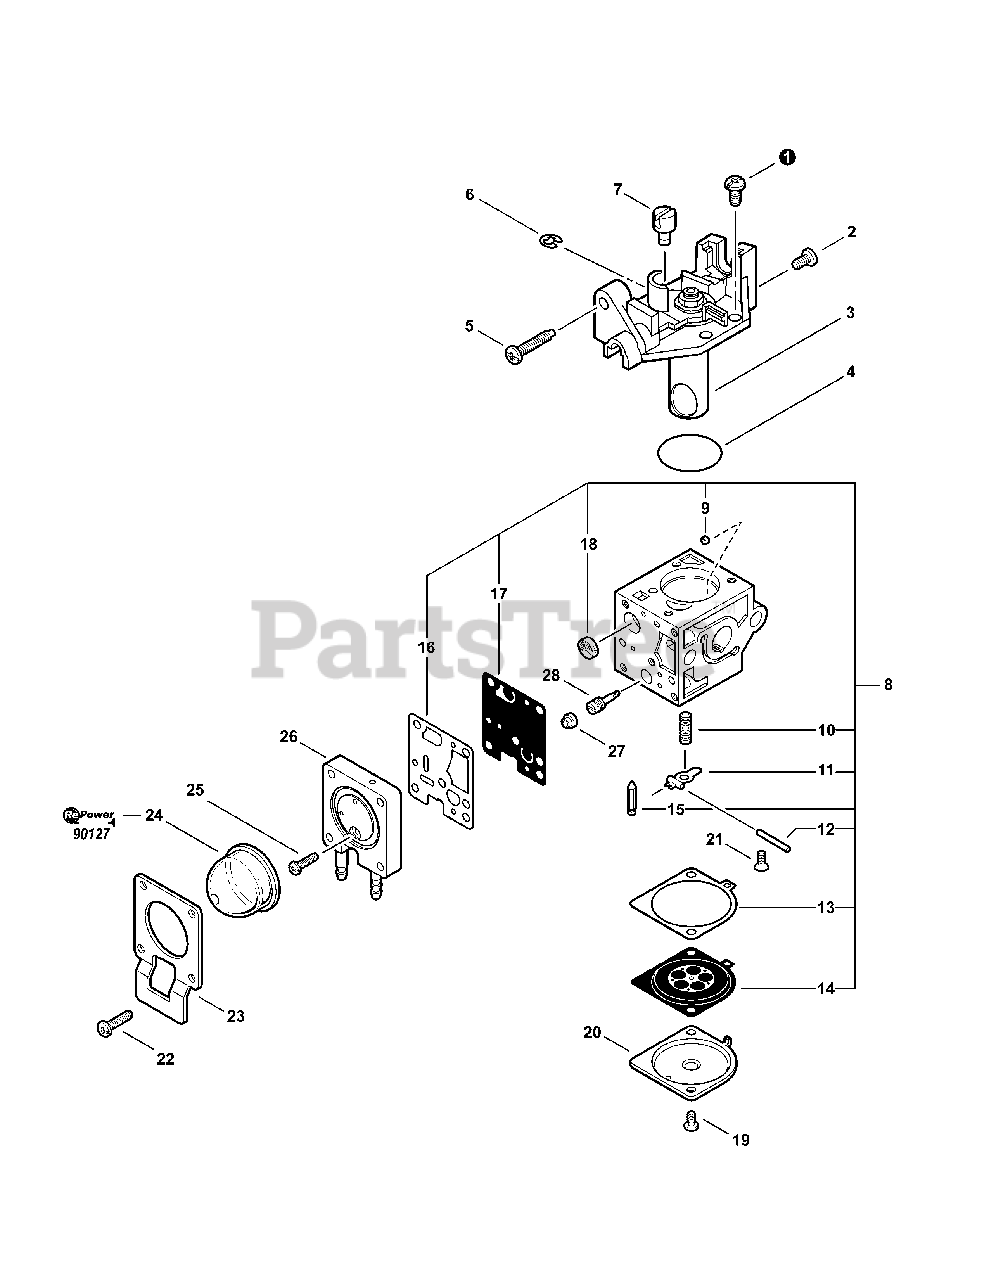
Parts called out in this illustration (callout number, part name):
3	COVER ASSY, ROTOR
5	SCREW, IDLE ADJUST
8	REPAIR KIT
9	GUIDE, ROLLER
10	SPRING, METERING LEVER
11	LEVER, METERING
12	PIN, METERING LEVER
13	DIAPHRAGM, METERING
14	GASKET, DIAPHRAGM
15	VALVE, INLET NEEDLE
16	GASKET, PUMP
17	DIAPHRAGM, PUMP
18	STRAINER
20	COVER, METERING DIAPHRAGM
23	RETAINER, PURGE BULB
24	BULB, PURGE
26	BODY ASSY, PURGE
28	NEEDLE, HIGH SPEED
